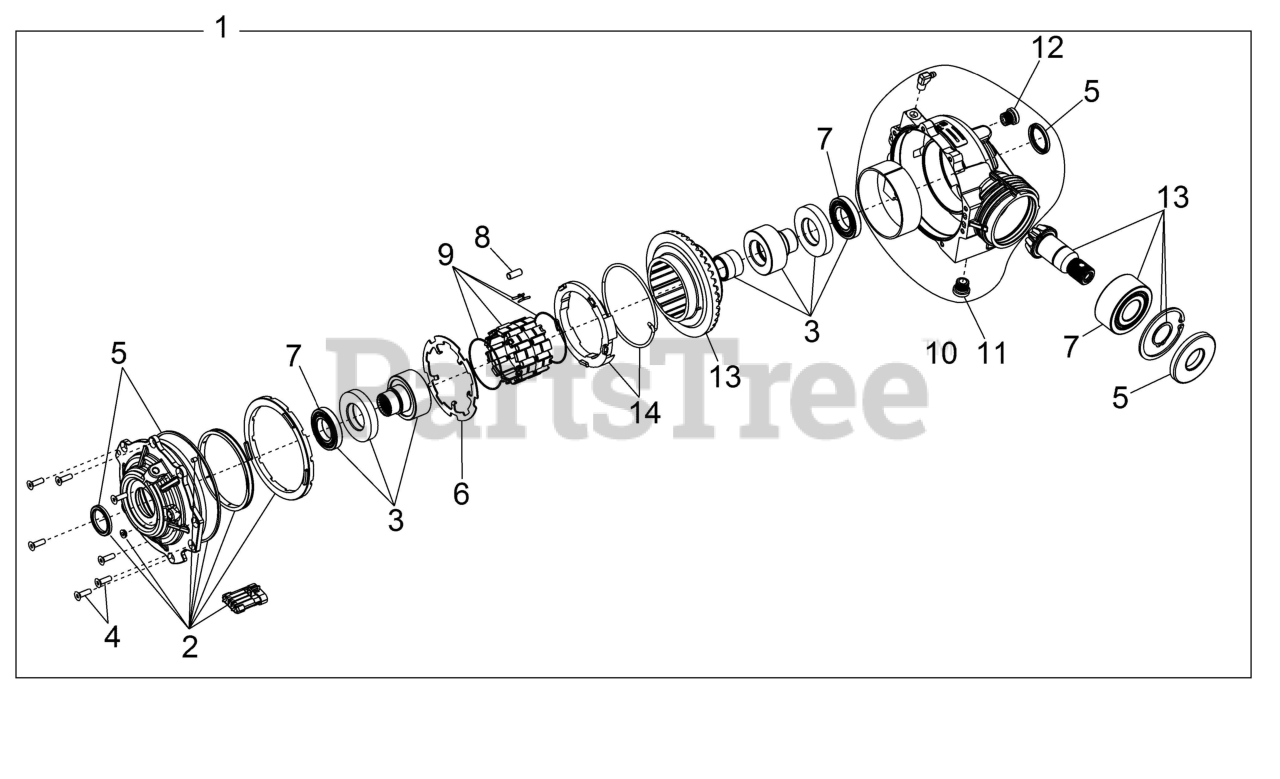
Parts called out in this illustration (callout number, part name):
1	ASM-GEARCASE,FRONT
2	ASM-COVER,OUTPUT
3	KIT-HUB,ASM
4	KIT-FASTENER
5	KIT-SEAL REPAIR
6	PLATE-4WD ARMATURE
7	BEARING-PINION,5306
8	K-CLUTCH ROLLS
9	ASSY, ROLL CAGE ZN
10	KIT-GEARCASE ASM
11	DRAIN PLUG(6203-95-010)
12	FILL PLUG(1300-04-001-T)
13	K-GEAR CLTCH HOUSING & PINION
14	K-TORSION SPRING & RETAINER
